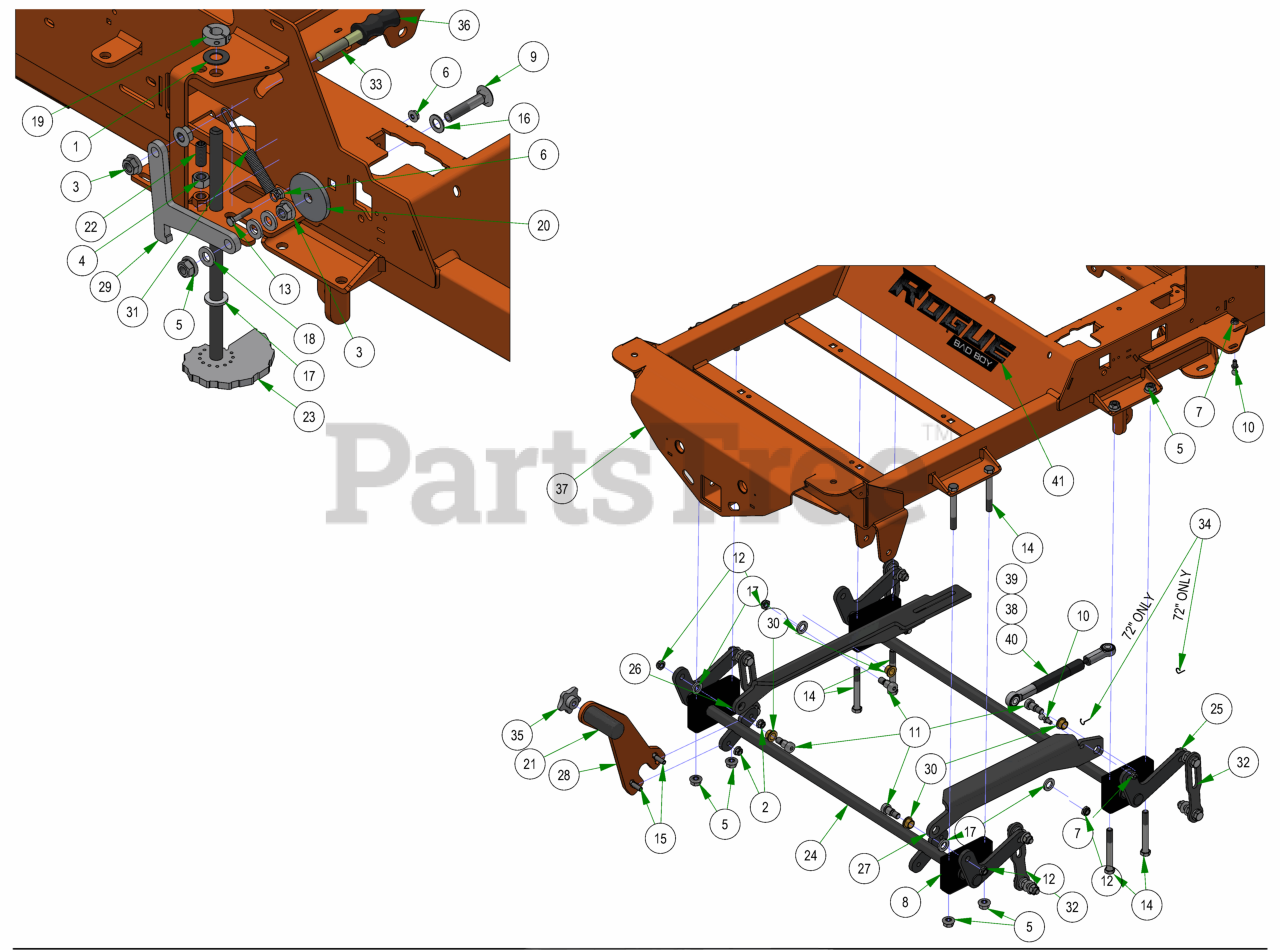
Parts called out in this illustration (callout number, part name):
1	.625 ID x 1.250 OD x .062 THK F/W Nylon
2	3/8-16 NYLON INSERT FLANGE LOCKNUT (GR.F) ZINC
3	1/2-13 HEX SERRATED FLANGE NUT HARD/ZINC
4	1/2-13 HEX NUT ZINC
5	1/2-13 NYLON INSERT FLANGE LOCKNUT ZINC
6	1/4-20 HEX SERRATED FLANGE NUT HARD/ZINC
7	5/16-18 HEX SERRATED FLANGE NUT HARD/ZINC
8	Pillow Block Assembly
9	2 1/2 x 1/2 Carriage Bolt
10	13mm Damper Ball Stud-Steering
11	5/8 X 5/8 SOCKET SHOULDER BOLT ZINC YELLOW
12	1/2-13 NYLON INSERT JAM LOCKNUT ZINC
13	1/4-20 X 1-1/4 HEX CAP SCREW (GR.5) ZINC
14	1/2-13 X 4 HEX CAP SCREW (GR.8) ZINC YELLOW
15	3/8-16 X 1-1/4 CARRIAGE BOLT ZINC
16	.517 SQ WDTH ID X .937 OD X .060 THICK F/W PHOS/OIL
17	.635 ID X 1.120 OD X .140 THICK FLAT WASHER NYLON
18	.505 ID X 1.000 OD X .125 THICK FLAT WASHER NYLON
19	5/8" Split Collar
20	MZ Deck Idler Spacer
21	Knurled Pedal
22	Dial Rod Plunger
23	2019 Outlaw Gen2 Deck Height Dial Rod Assy
24	2019 Outlaw Actuator - Front
25	2019 Outlaw Actuator - Rear
26	2019 Actuator Linkage – Right – Black
27	2019 Actuator Linkage - Left - Black
28	Foot Lift Upright Lever
29	2019 Outlaw Deck Travel Lock
30	.627 ID X .753 OD X .500 LGTH X 1.000 FLG OD X .094 FLG THICK FLANGED BEARING OIL-IMPREG BRNZ
31	Brake Spring
32	Deck Hanger Assembly
33	Seat Bracket Pin
34	Security Ring - PC744
35	Foot Pedal Knob 1/2-13
36	Travel Lock Rubber Grip
37	2023 Rogue Frame - Painted
38	200 lb Gas Spring- 54" Deck outlaw
39	250lb Gas Spring - 61" Deck
40	300lb Gas Spring - 72" Deck
41	Rogue back Plate & Front Decal
